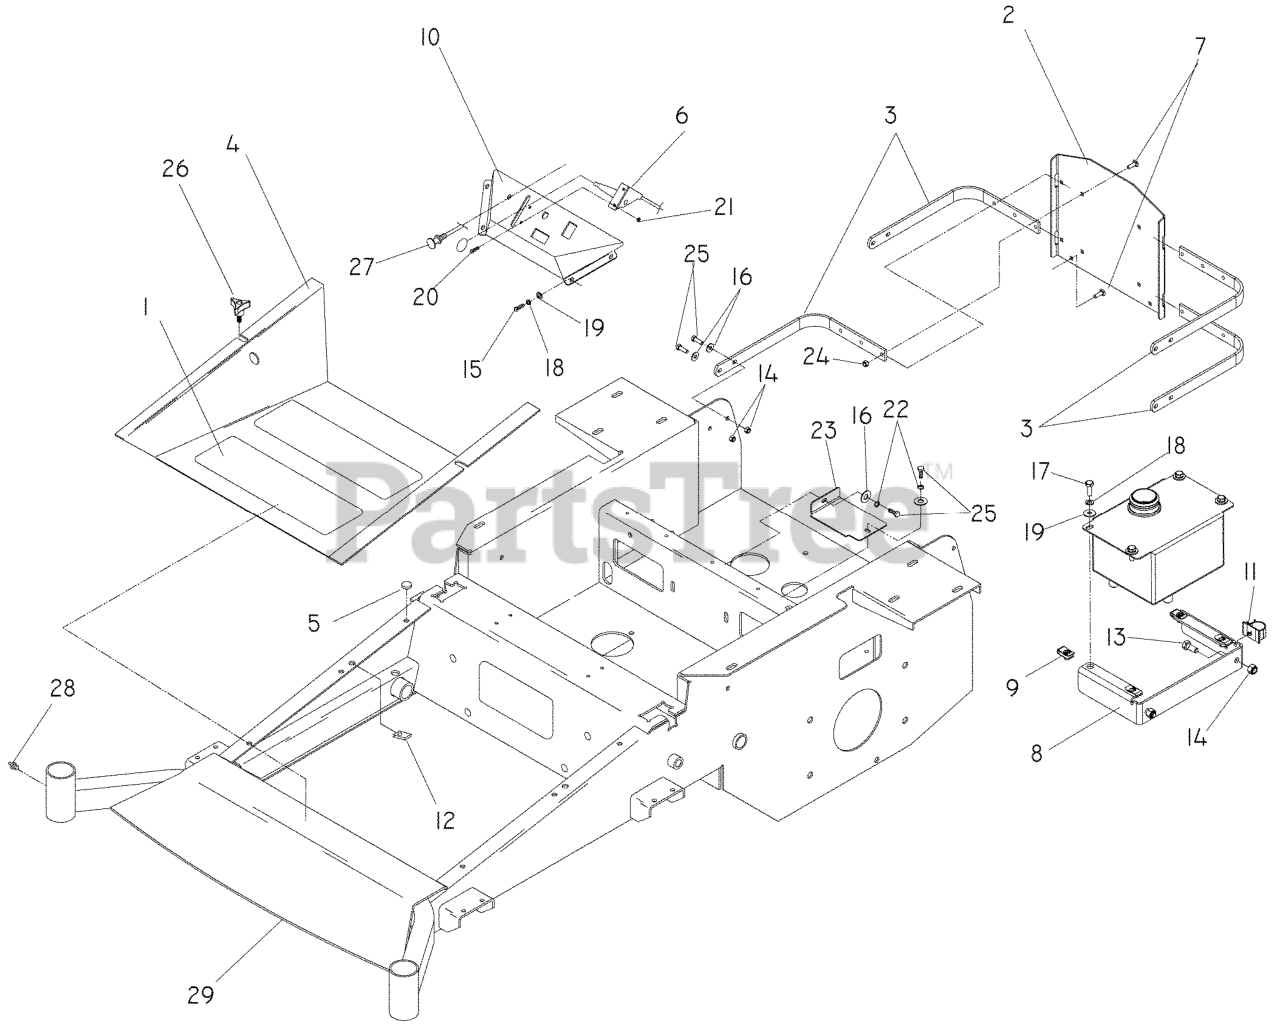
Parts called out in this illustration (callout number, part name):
1	ANTI-SKID PAD
2	XP GUARD, BLACK
3	ENGINE SHROUD BRKT
4	FOOT PLATE WIDMT
5	GROMMET, BUMPER
6	THROTTLE CONTROL W/BALL KNOB
7	BOLT 5/16C X 3/4" CARRIAGE
8	TANK MOUNT
9	1/4C - U TYPE RETAINER
10	CONSLE, ORANGE
11	PUSH-MOUNT WIRE CLIP
12	U-CLIP 5/16-18 NUT RETAINER
13	HCS 5/16C X 3/4
14	NUT 5/16 NYLOC
15	SCREW 1/4 X 5/8
16	WASHER 5/16 FLAT
17	HCS 1/4C X 3/4 HCS
18	LOCKWASHER 1/4"
19	WASHER 1/4 FLAT
20	HCS #10-24 X 1/2
21	NUT 10-24 NYLOC
22	WASHER.LOCK.HVY.HLCL.SPR.5/16
23	IDLER COVER
24	NUT 5/16C CENTERLOCK
25	HCS 5/16C X 1
26	KNOB W/STUD
27	CONTROL-CHOKE 57"
28	ZERK
29	FRAME W/DECALS
